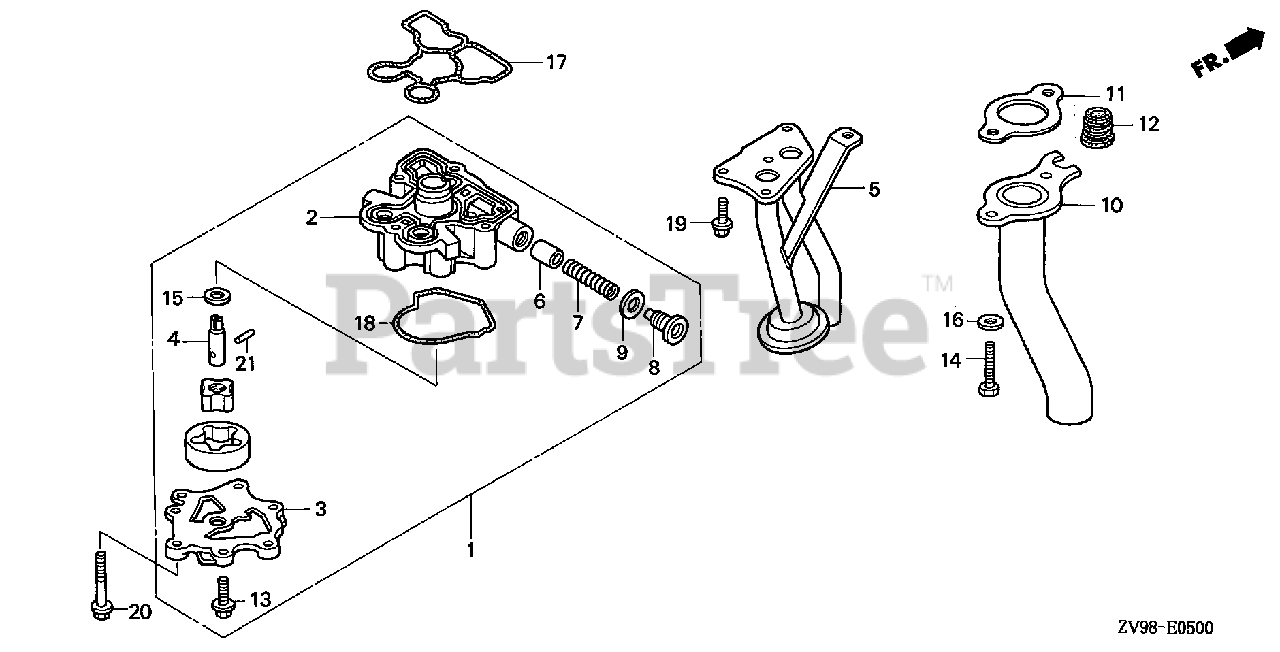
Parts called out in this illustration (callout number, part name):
1	PUMP ASSY., OIL
2	BODY, OIL PUMP
3	COVER, OIL PUMP
4	SHAFT, OIL PUMP
5	STRAINER, OIL
6	VALVE, RELIEF
7	SPRING, RELIEF VALVE
8	BOLT, SEALING (14MM)
9	WASHER, SEALING (14MM)
11	GASKET, EX. PIPE
12	GROMMET, WATER TUBE
13	BOLT, FLANGE (6X18)
13	BOLT, FLANGE (6X18) (CT200)
14	BOLT, HEX. (8X25)
15	WASHER, THRUST (11MM)
16	WASHER, PLAIN (8MM)
17	O-RING, PUMP COVER
18	O-RING, PUMP COVER
19	BOLT, FLANGE (6X16)
20	BOLT, FLANGE (6X45)
21	ROLLER (4X15.8)
